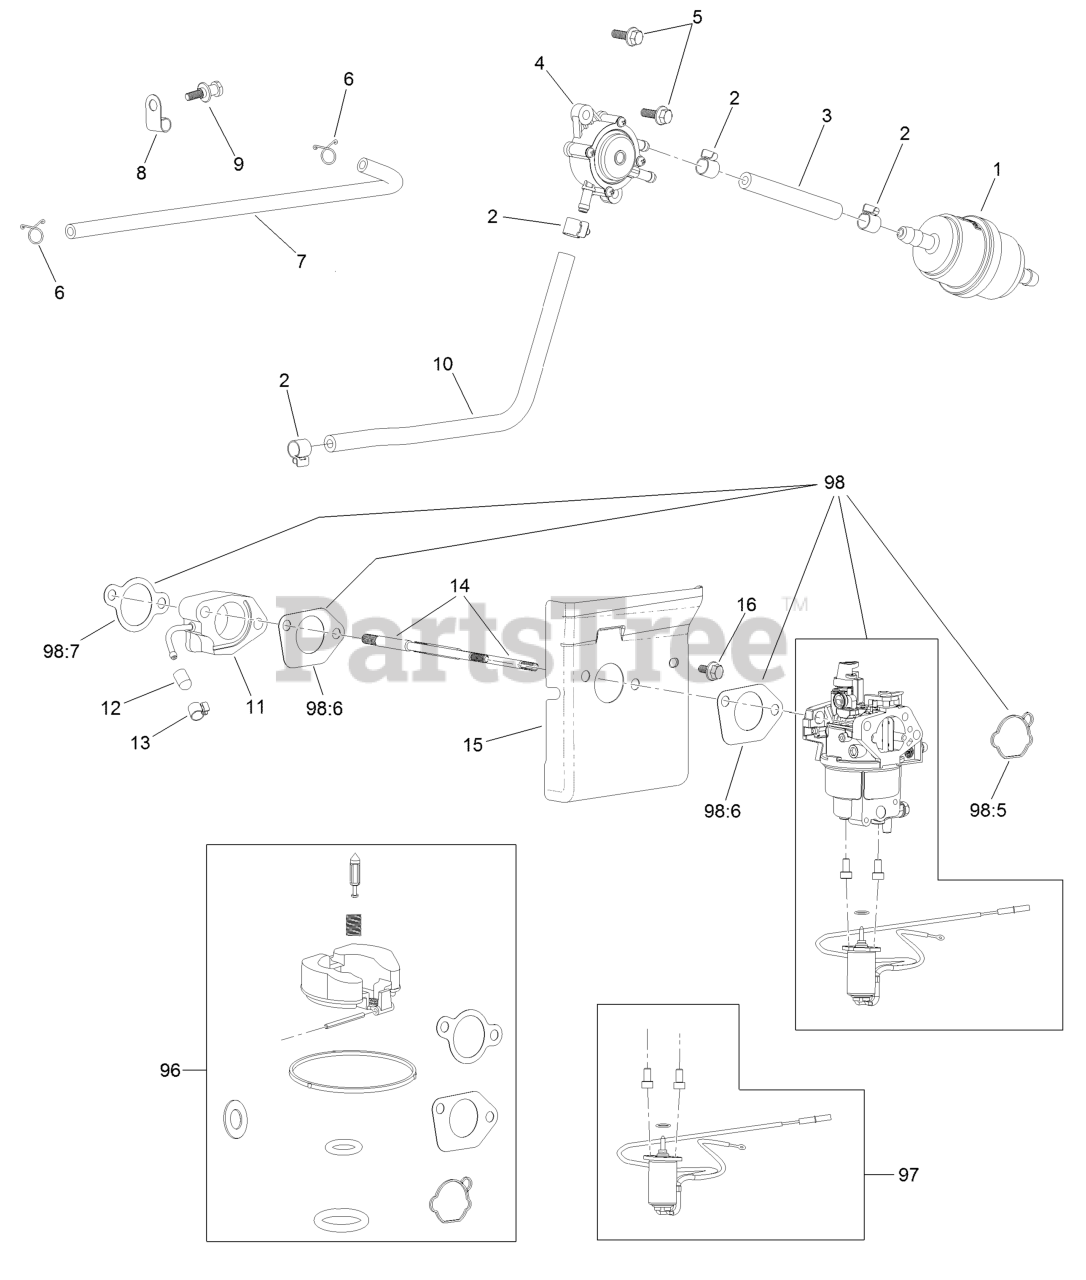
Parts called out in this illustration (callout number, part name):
1	FILTER-FUEL
2	CLAMP-FUEL LINE
3	LINE-FUEL
4	PUMP-PULSE, FUEL
5	SCREW-HHF
6	CLAMP-HOSE
7	LINE-PULSE
8	CLAMP-J
9	SCREW-SHOULDER, HH
10	LINE-FUEL
11	INSULATOR-CARBURETOR
12	CAP-SEAL
13	CLAMP-HOSE
14	STUD-MOUNT, CARBURETOR
16	SCREW-HHF
96	CARB REPAIR KIT WITH GASK
97	SOLENOID KIT
98:5	GASKET-CARBURETOR
98:6	GASKET-CARBURETOR
98:7	GASKET-CARBURETOR
